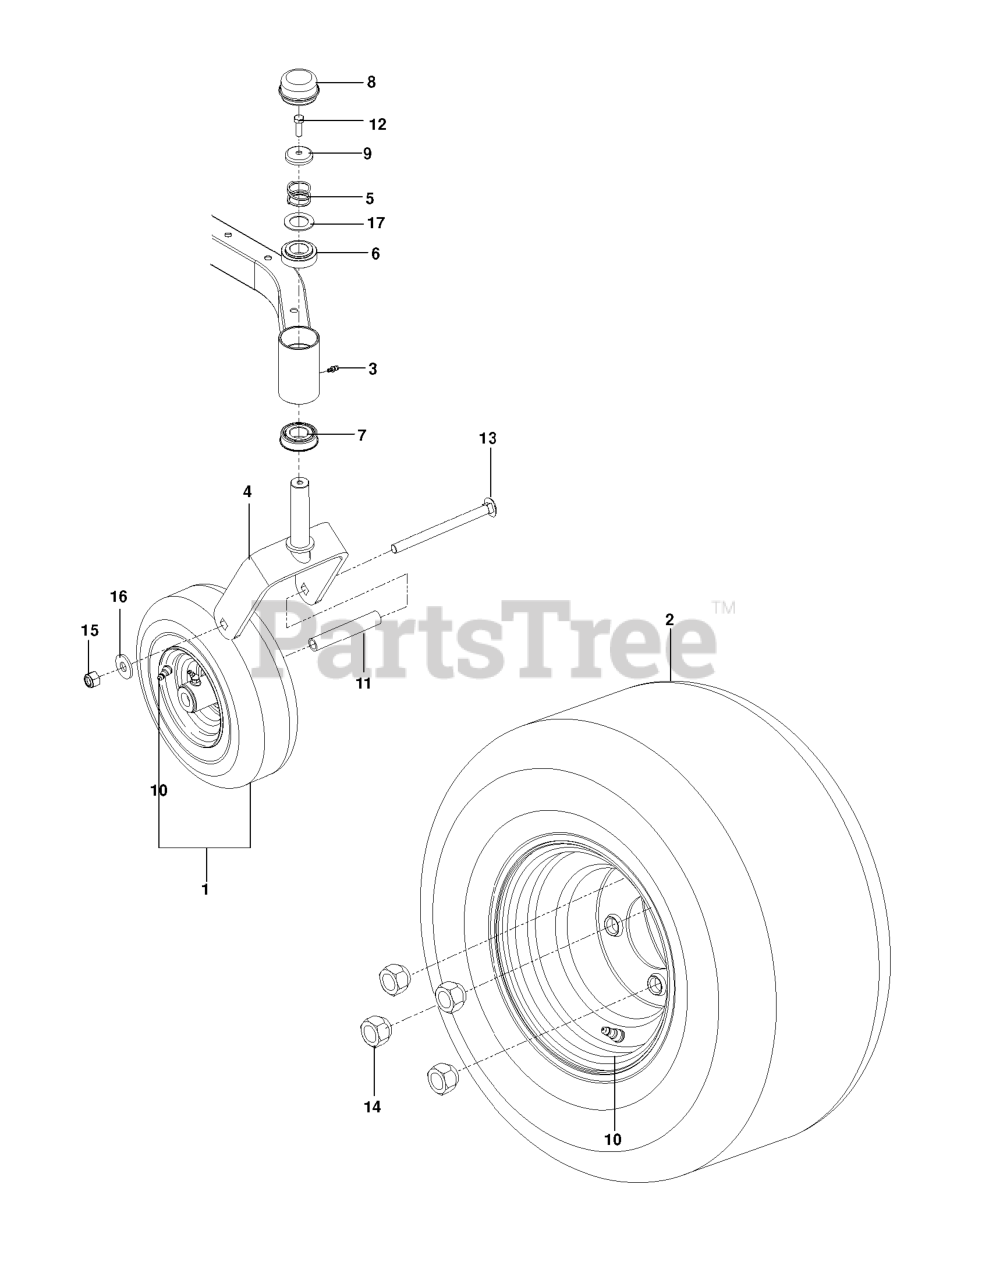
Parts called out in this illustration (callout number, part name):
1	WHEEL ASSY, WIDE, RZ
2	WHEEL.ASSEM.18X8.5-8.KENDA.ZTR
3	ZERK, 3/16, DRIVE IN
4	YOKE.CASTER.ORANGE
5	SPRING, CASTER
6	BUSHING, CASTER
7	BEARING FLANGED
8	GREASE CAP
9	CASTER.PLUG
10	VALVE STEM TR-412
11	SPACER, PIVOT
12	5/16-18X1 HHB G5W/NY
13	RHSNB 1/2-13 X 7.5
14	LUG NUT 1/2F
15	NUT 1/2-13 HEX CNTRLK GR 5 ZD
16	WASHER.9/16 X 1 3/8 X 12 GA.
17	WASHER, 1.025 ID X 1.64
